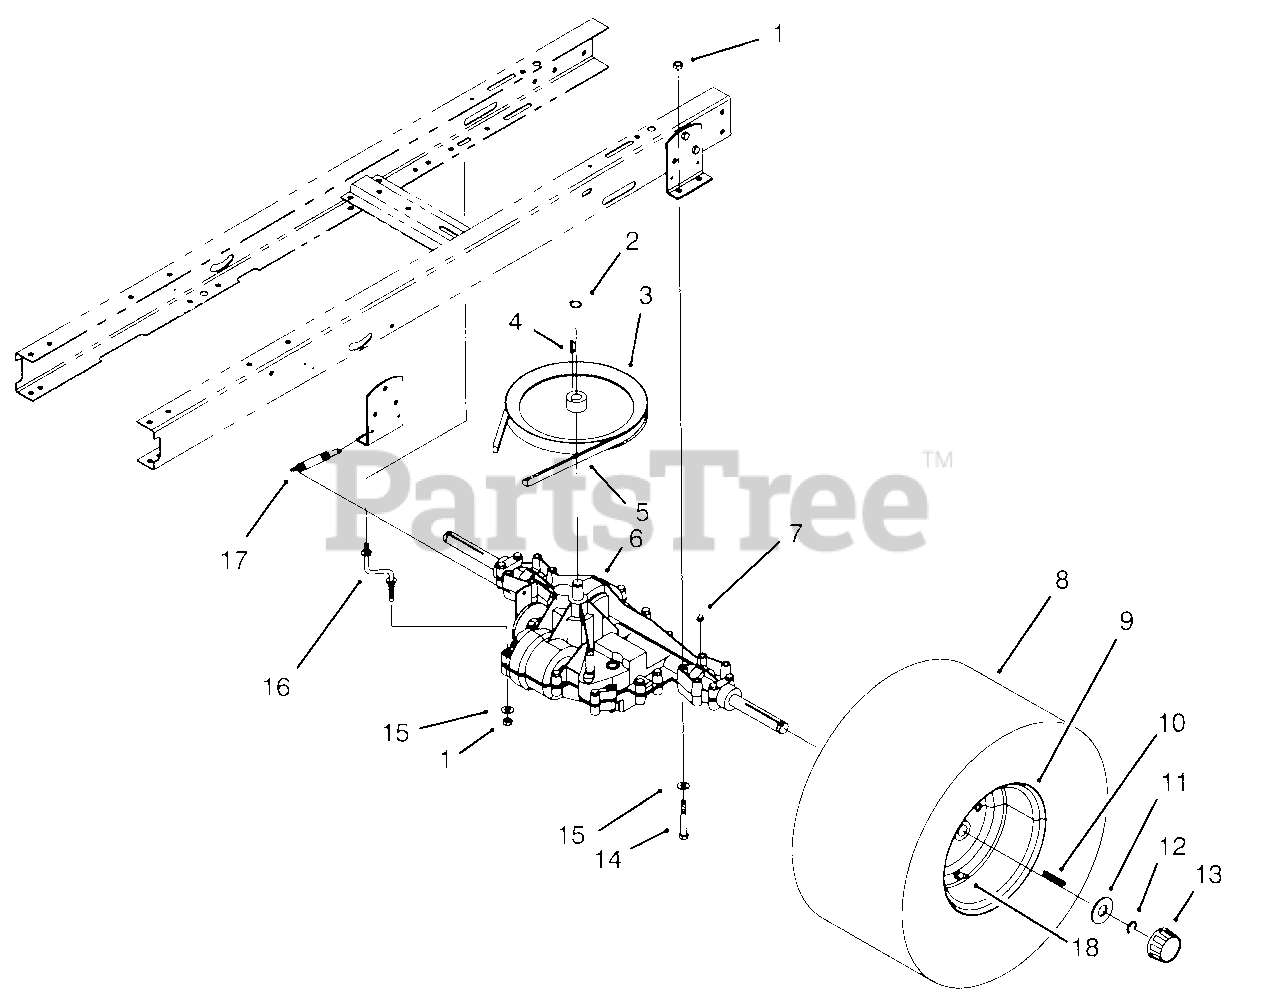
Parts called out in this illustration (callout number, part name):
1	Nut-Lock
2	Ring-Snap
3	Pulley-Transmission
4	Key-Woodruff
5	V-Belt-Traction (Model No. 81182 Only)
6	Transaxle
7	Fitting-Grease
8	Tire (Model No. 81182 Only)
9	Rim (Model No. 81180 Only
10	Key-Square
14	Screw-Hex Hd. Cap
15	Washer-Flat
16	Strap-Torque
17	Spring-Brake Return
18	Valve Stem w/Cap
